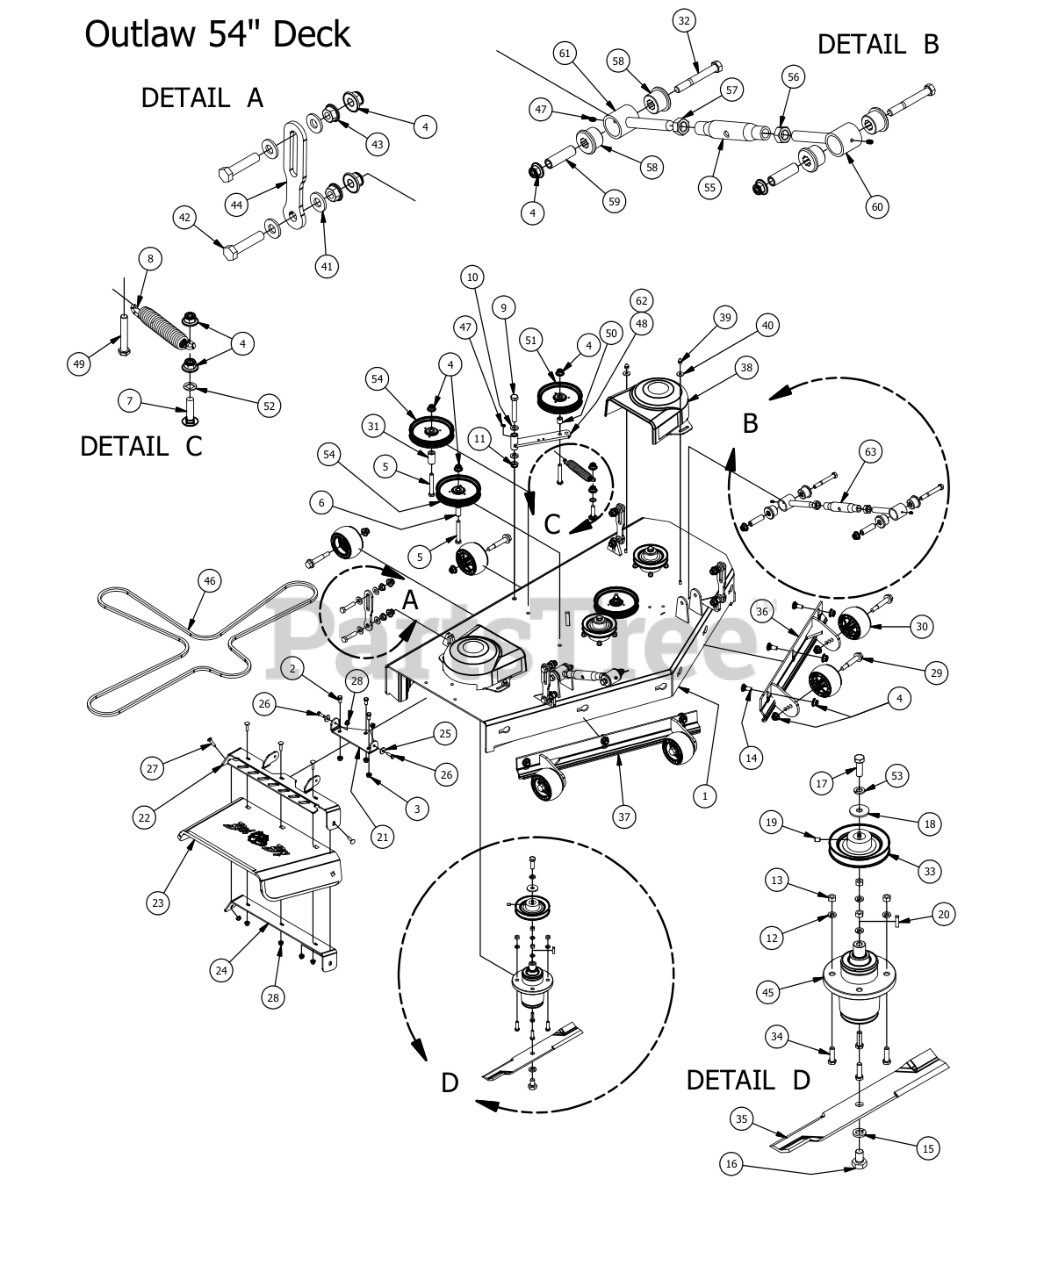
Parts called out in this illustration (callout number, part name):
1	2015 54" Deck
2	3/8" x 3/4" Hex Bolt
3	3/8" Flange Nut
4	1/2-13 Nylon Flange Nut
5	1/2 x 3 1/2 Flange Bolt Grade 8
6	.502 ID X.750 OD X 1.500 Long Spacer
7	1/2 x 2" Carriage Bolt
8	2015 Deck Idler Spring Outlaws
9	5/8" x 4" Hex Bolt
10	.630 ID Plastic Washer
11	5/8-11 Nylon Insert Jam Half Nut
12	3/8 Lockwasher Zinc
13	3/8-16 Hex Nuts Zinc
14	1/2" x 1 1/4 Carriage Bolt
15	5/8" Lock Washer
16	5/8" x 1 1/2" Grade 8 Hex Bolt (Fine)
17	1/2"-20 x 1 1/2 - Grade 5 Fine Thread Bolt
18	1/2 Belleville Washer
19	5/16 Set Screw
20	1/4" x 1" Key
21	Discharge Chute Hanger (deck mounted)
22	60" Discharge Chute Upper Hanger
23	Rubber Discharge Chute
24	60" Discharge Lower Bracket
25	.360 ID Plastic Washer
26	5/16" x 1" Bolt
27	5/16" x 1 1/4" Carriage Bolt
28	5/16" Nylock Flange Nut Zinc
29	Deck Wheel Bolt
30	Anti-Scalp Rollers
31	1 3/4" Pulley Spacer
32	1/2" x 4" Bolt (Grade 8)
33	5" Spindle Deck Pulley
34	3/8" x 1 1/4" Hex Bolt
35	54" Deck Fusion Blade For Outlaw
36	54 Deck Adustable Front (Left)
37	54 Deck Adustable Front (Right)
38	Pulley Cover
39	Acorn nut-pulley Cover
40	.360 ID Plastic Washer-Black
41	.505 Nylon Spacer
42	1/2-13X 2-1/4 GR Hex Bolts
43	1/2" Flange Nut
44	Deck_Hanging_Tab
45	OUTLAW SPINDLE ASSEMBLY
46	60" ZT Deck Belt
47	1/4" Press in Grease Fitting
48	Deck Idler
49	1/2-13 x GR 5 Hex Bolt Zinc
50	Spacer 3/4 OD x 1/2 ID x 3\4 Length
51	5-3/4 Idler Pulley-Don Dye
52	.517 Square Hole Round Washer
53	1/2" Lock Washer
54	5-3/4 Idler Pulley-Capitol Stampings
55	2015 Outlaw Toplink Body
56	3/4-10 Left-Handed Hex Nuts Zinc
57	3/4-10 Hex Nuts Zinc
60	Turn Left-Handed
61	Right-Handed End
62	Deck Idler Assembly - Includes parts: 4,47,48,50,51
63	Turnbuckle Assembly
